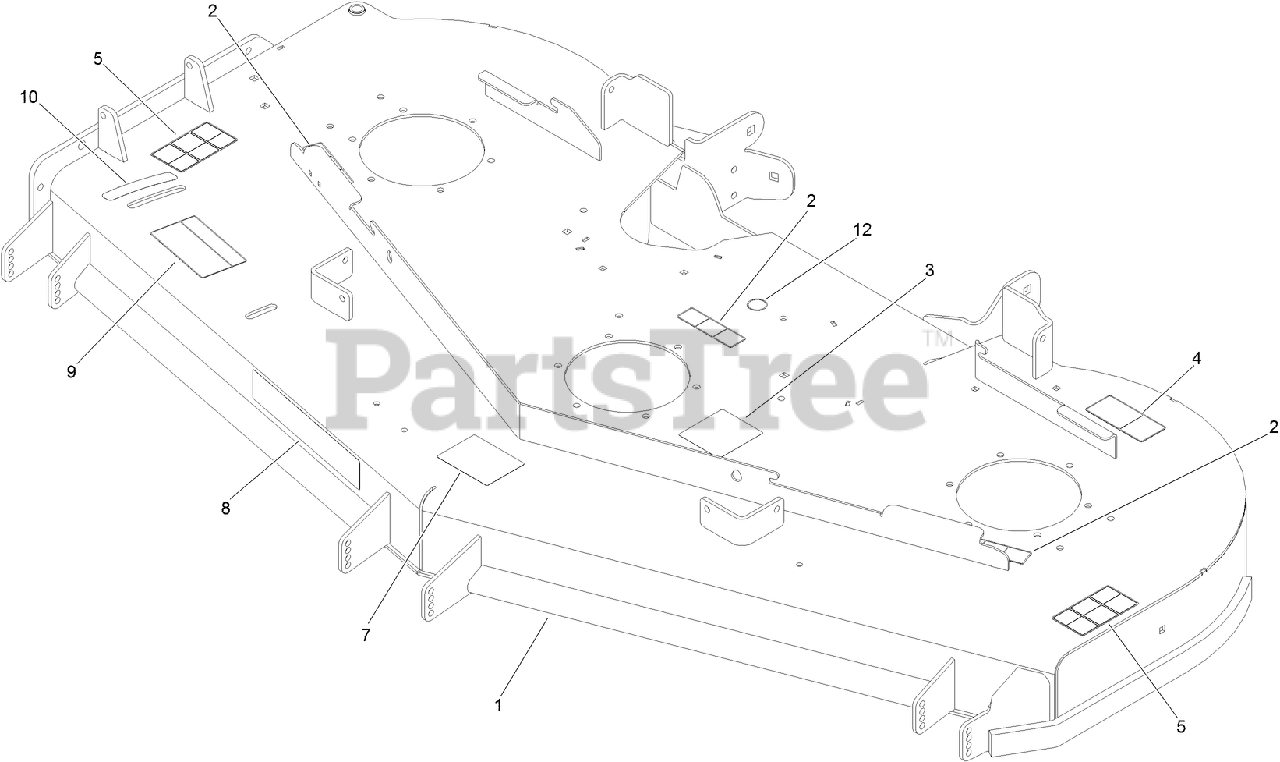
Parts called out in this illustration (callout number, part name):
1	DECK DECAL ASM
2	DECAL-COVER, MISSING
3	DECAL-ROUTING, DECK BELT
4	DECAL-TORQUE, BLADE BOLT
5	DECAL-DANGER
7	DECAL-SCALP, ANTI
9	DECAL-ADJUSTMENT, BAFFLE
10	DECAL-SETTING, BAFFLE
12	DECAL-GREASE
